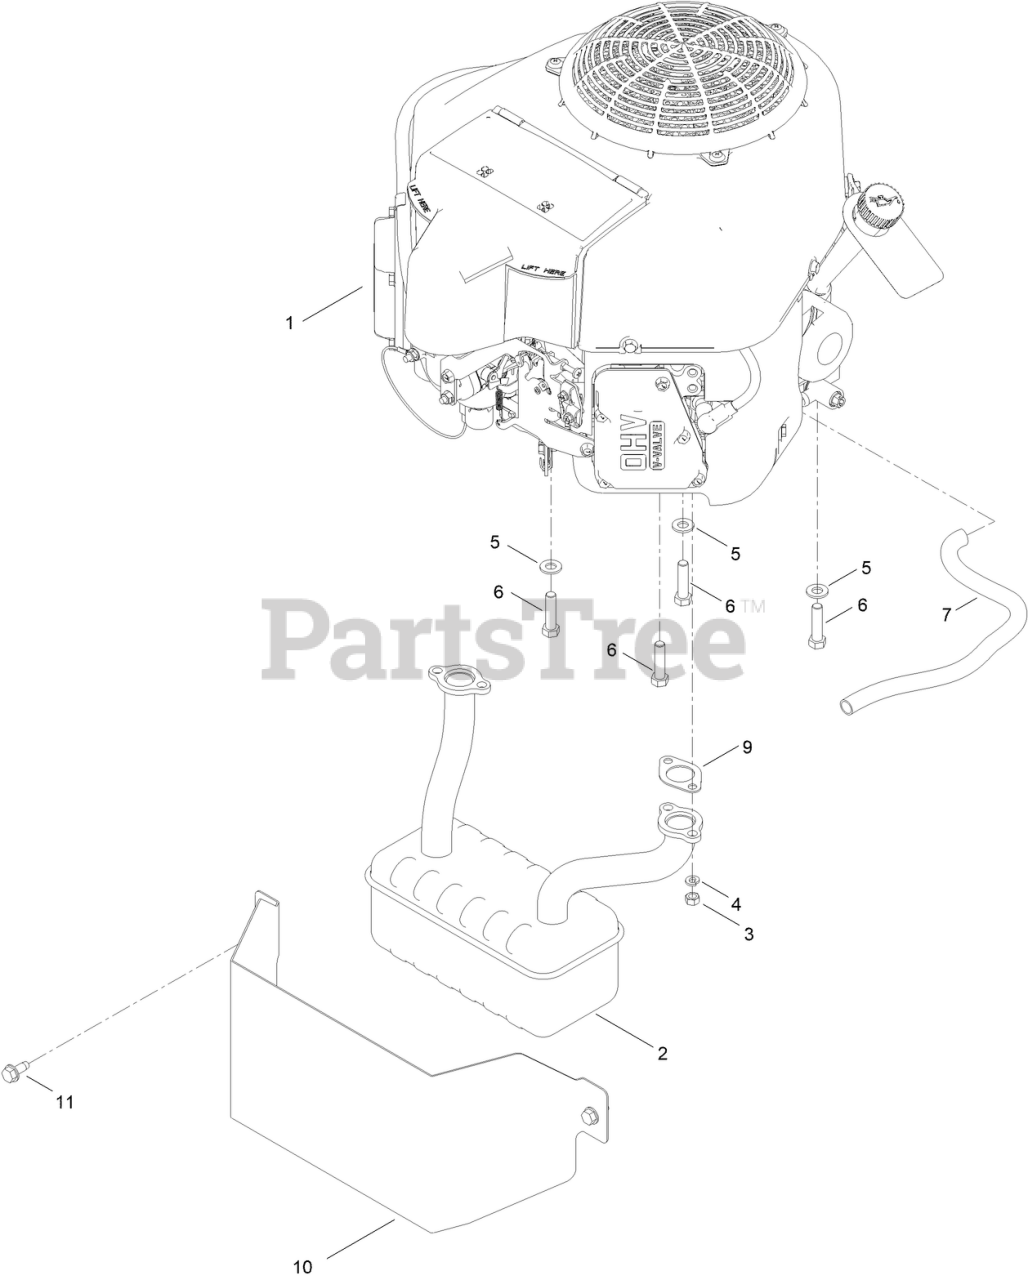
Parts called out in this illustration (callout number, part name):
1	ENGINE-KAWASAKI FR691
2	MUFFLER
4	WASHER-LOCK
5	WASHER-FLAT
6	BOLT-HH
7	TUBE-DRAIN, OIL
9	GASKET-EXHAUST
10	HEAT SHIELD - MUFFLER
11	SCREW-HWHTF
